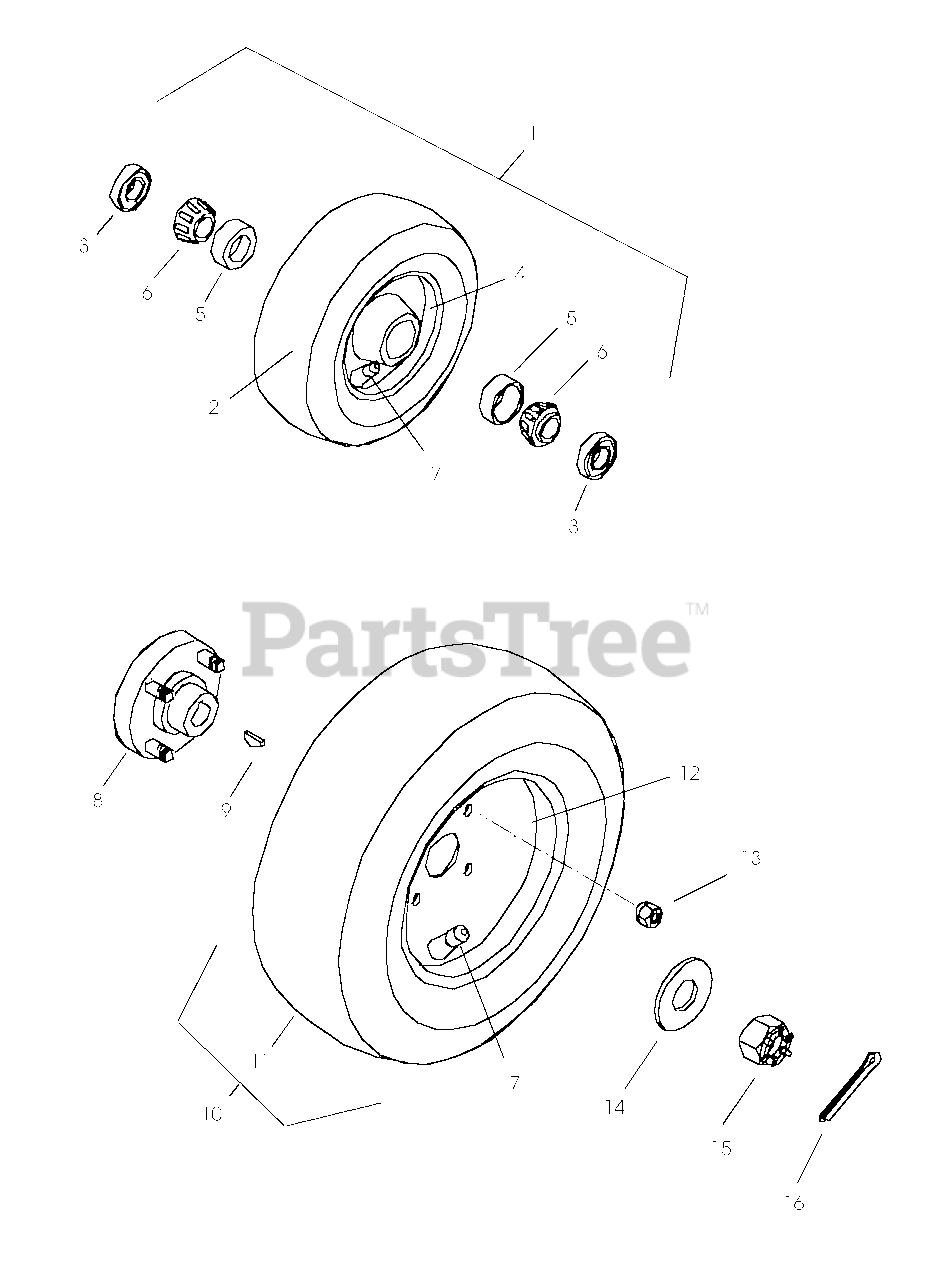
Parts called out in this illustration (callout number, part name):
1	Tire/Wheel Assembly 4.80-8
2	Tire 4.8-8
3	Seal
4	Wheel Assembly 4.8x8
5	Bearing-Cup 1.980 x 4.20
6	Bearing-Cone 1.0 x .58
7	Valve Stem Assembly
8	Hub w/studs
9	Key-Woodruff .25 x 1.0 x 7.00
10	Tire/Wheel Assembly 8.50-8 x 18
11	Tire 18-8.5x8
12	Wheel 18-8.5x8
13	Nut-Lug .50-20
14	Washer-Flat-Steel .755 x 1.375 x .062
15	Nut-Hex-Slotted .75-20
16	Pin-Cotter .12 x 1.25
